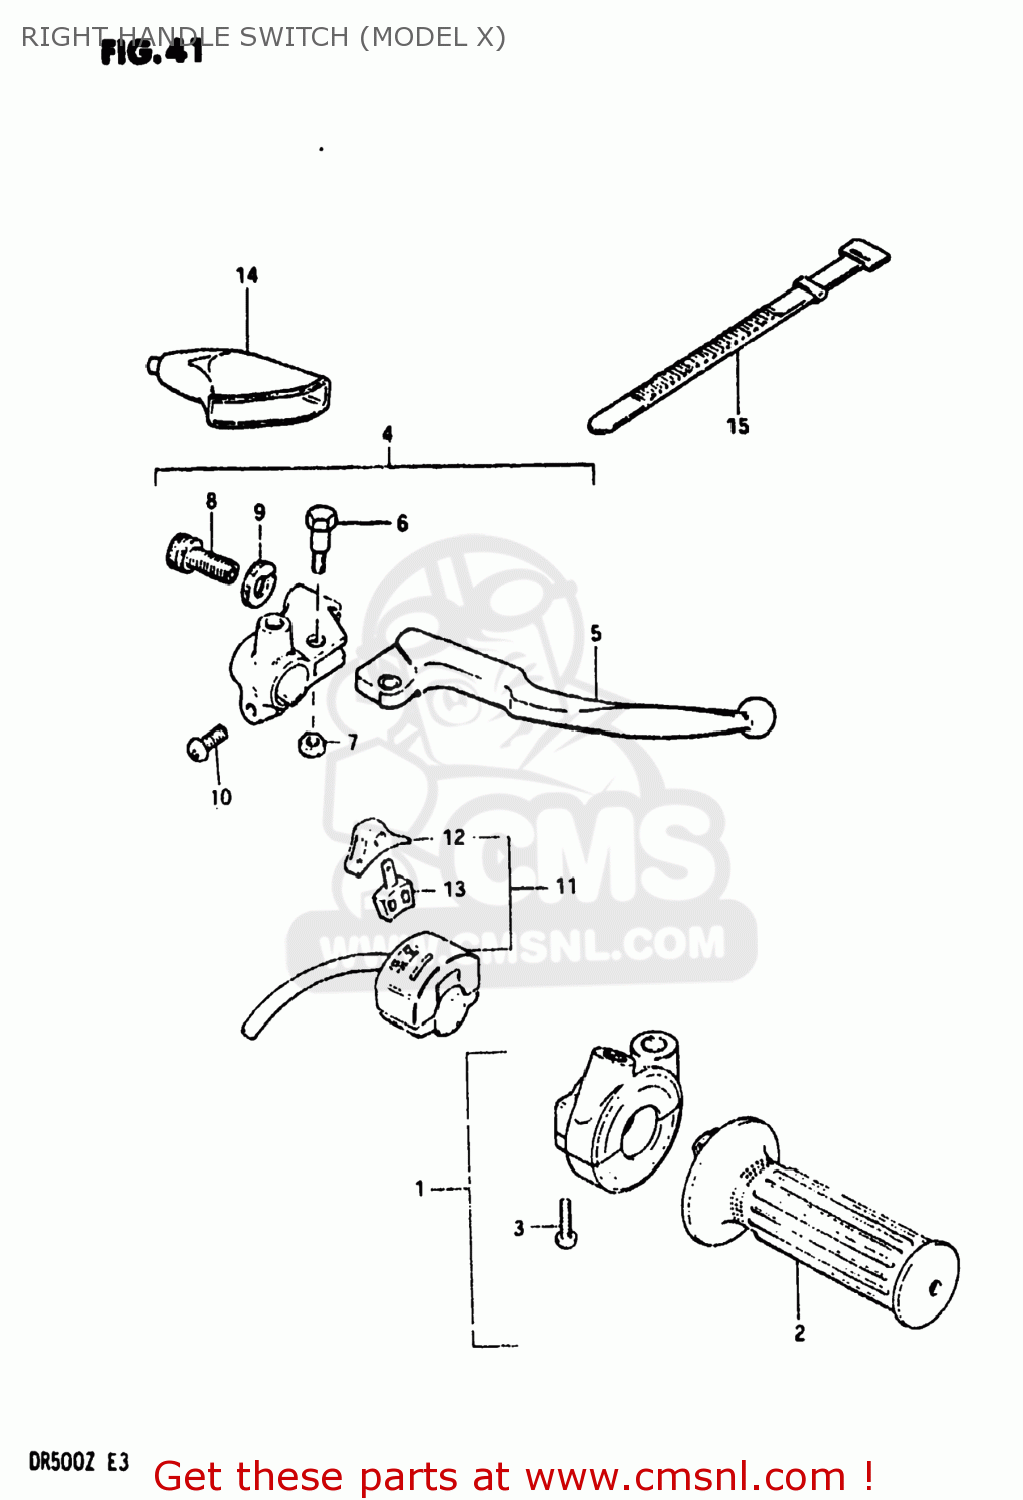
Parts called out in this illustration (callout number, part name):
1	CASE ASSY,THROTTLE
2	GRIP,THROTTLE
3	SCREW 5X20
4	LEVER ASSEMBLY,BRAKE
5	LEVER,BRAKE
6	BOLT,LEVER
7	NUT
8	ADJUSTER,CABLE
9	NUT,CABLE ADJUSTER
10	SCREW
11	SWITCH ASSEMBLY,LIGHTING
12	KNOB,LIGHTING & DIMMER
13	BLOCK,LIGHTING/DIMMER
14	COVER,CLUTCH LEVER
15	CLAMP(L:120)
